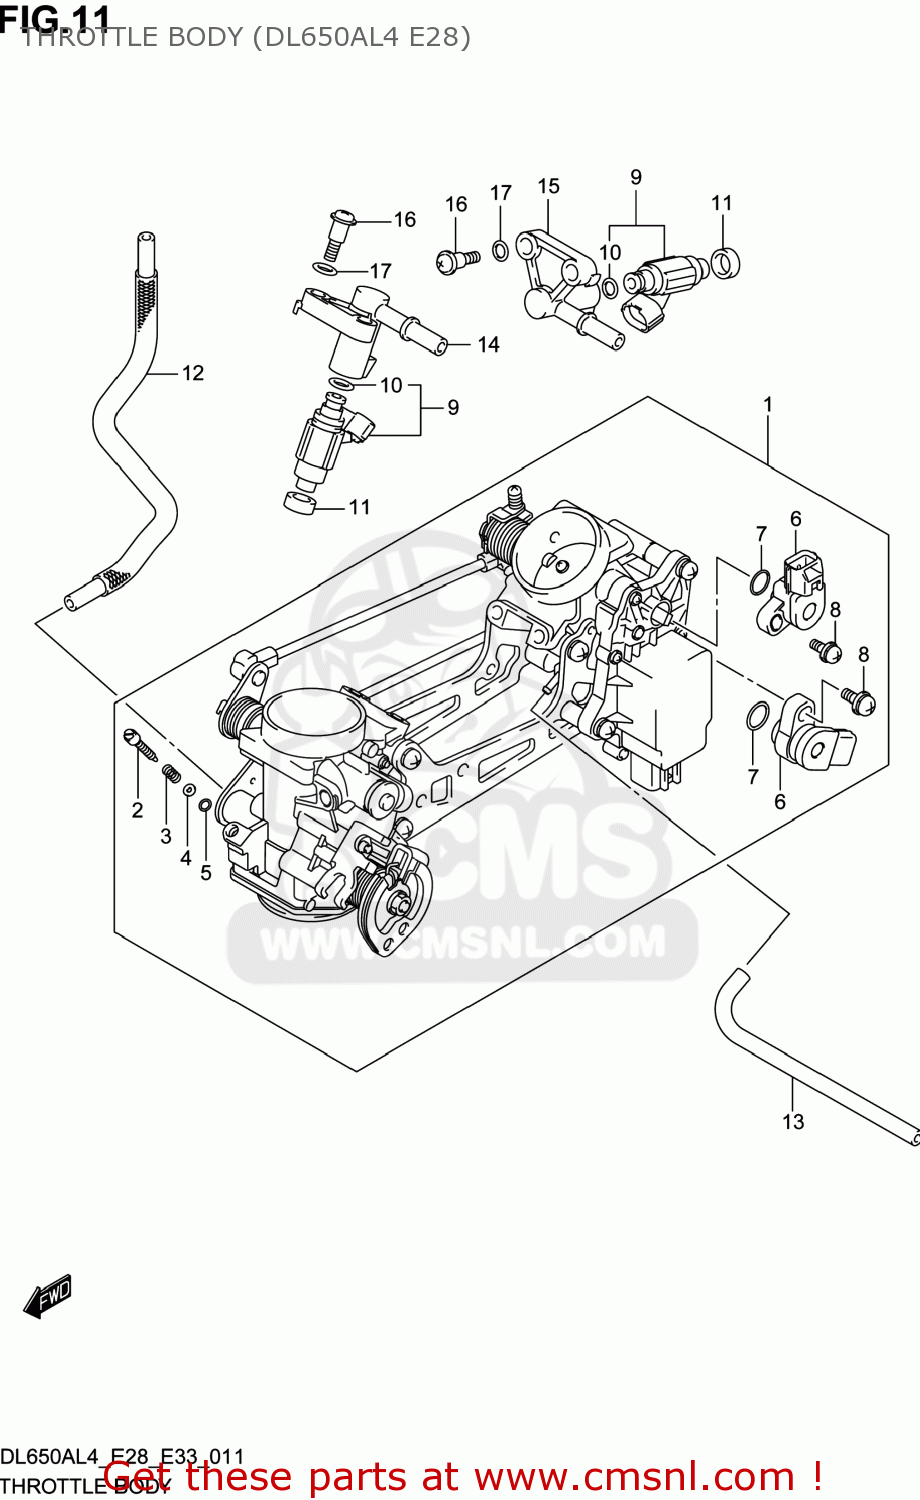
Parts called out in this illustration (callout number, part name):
1	BODY ASSY,THROTTLE
2	SCREW
3	SPRING,THROTTLE SCREW
4	WASHER
5	O RING,PILOT AIR SCREW
6	SENSOR
7	O RING
8	SCREW
9	INJECTOR ASSY
10	O-RING
11	SEAL
12	HOSE
13	HOSE
14	DELIVERY PIPE
15	DELIVERY PIPE
16	SCREW
17	PACKING (NAS)
